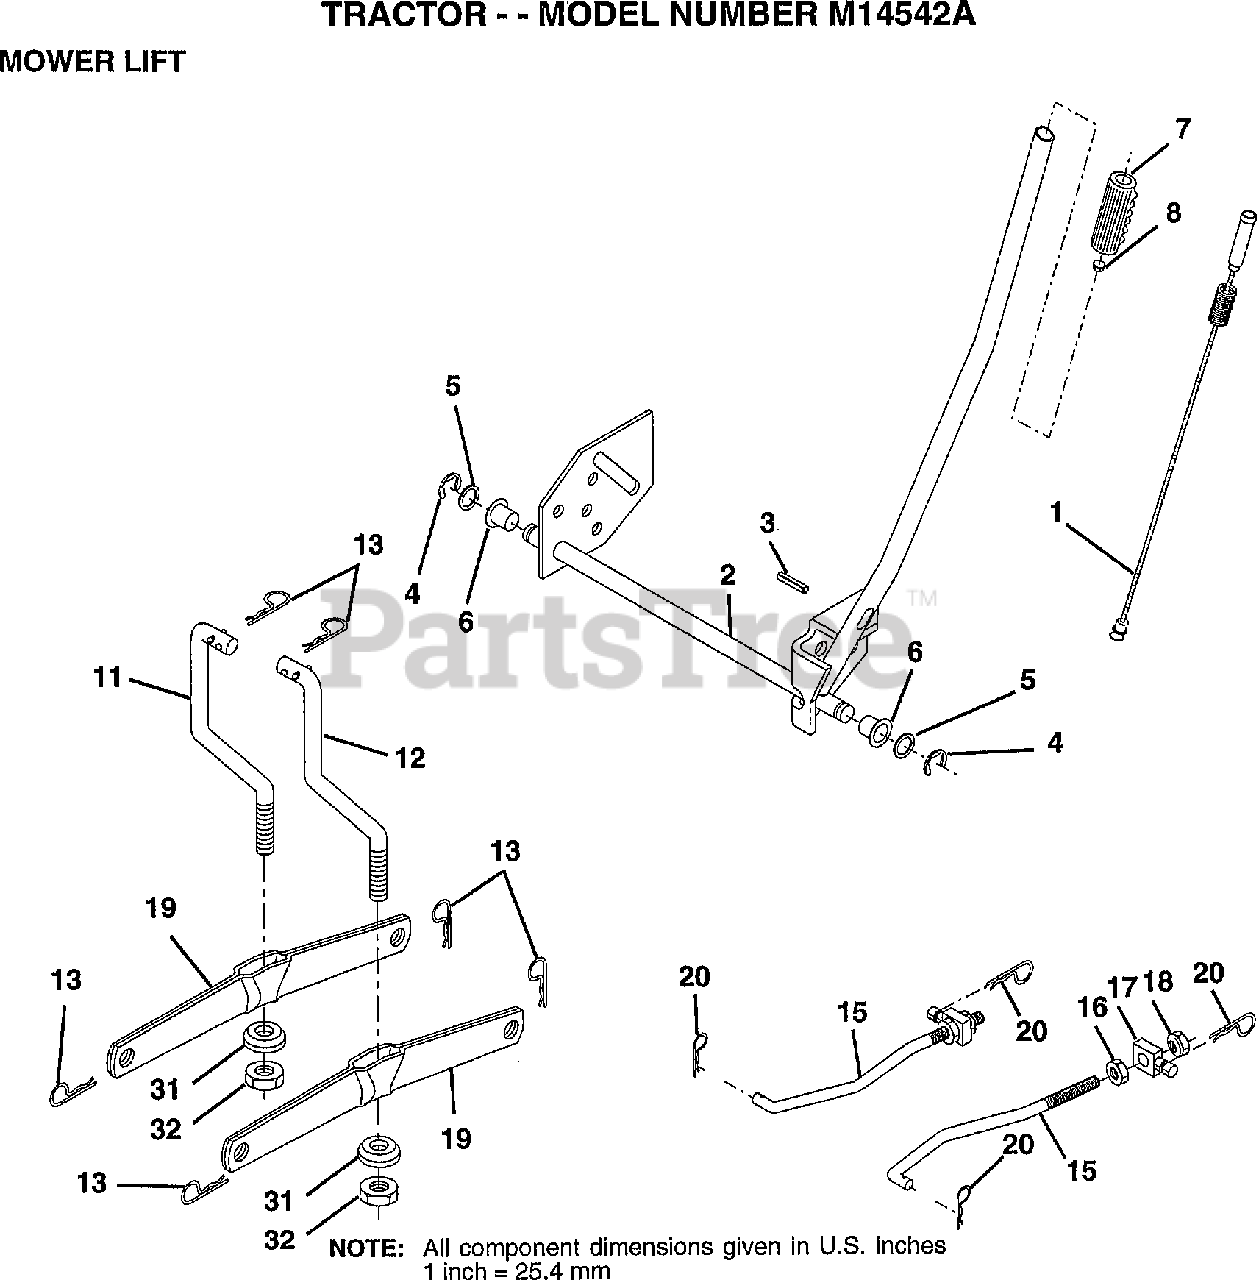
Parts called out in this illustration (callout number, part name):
1	WIRE ASM W.SPRING
2	"SHAFT ASM LIFT,RH"
3	PIN-GROOVE LT
5	WASHER
6	NYLON BEARING
7	GRIP
15	LINK.FRONT
16	NUT
17	TRUNION
18	NUT.LK.W/WSH.1/2.
19	ARM SUSP REAR
20	RETAINER.SPRING
31	BEARING PVT LH
32	NUT.CROWNLOCK.3/8
